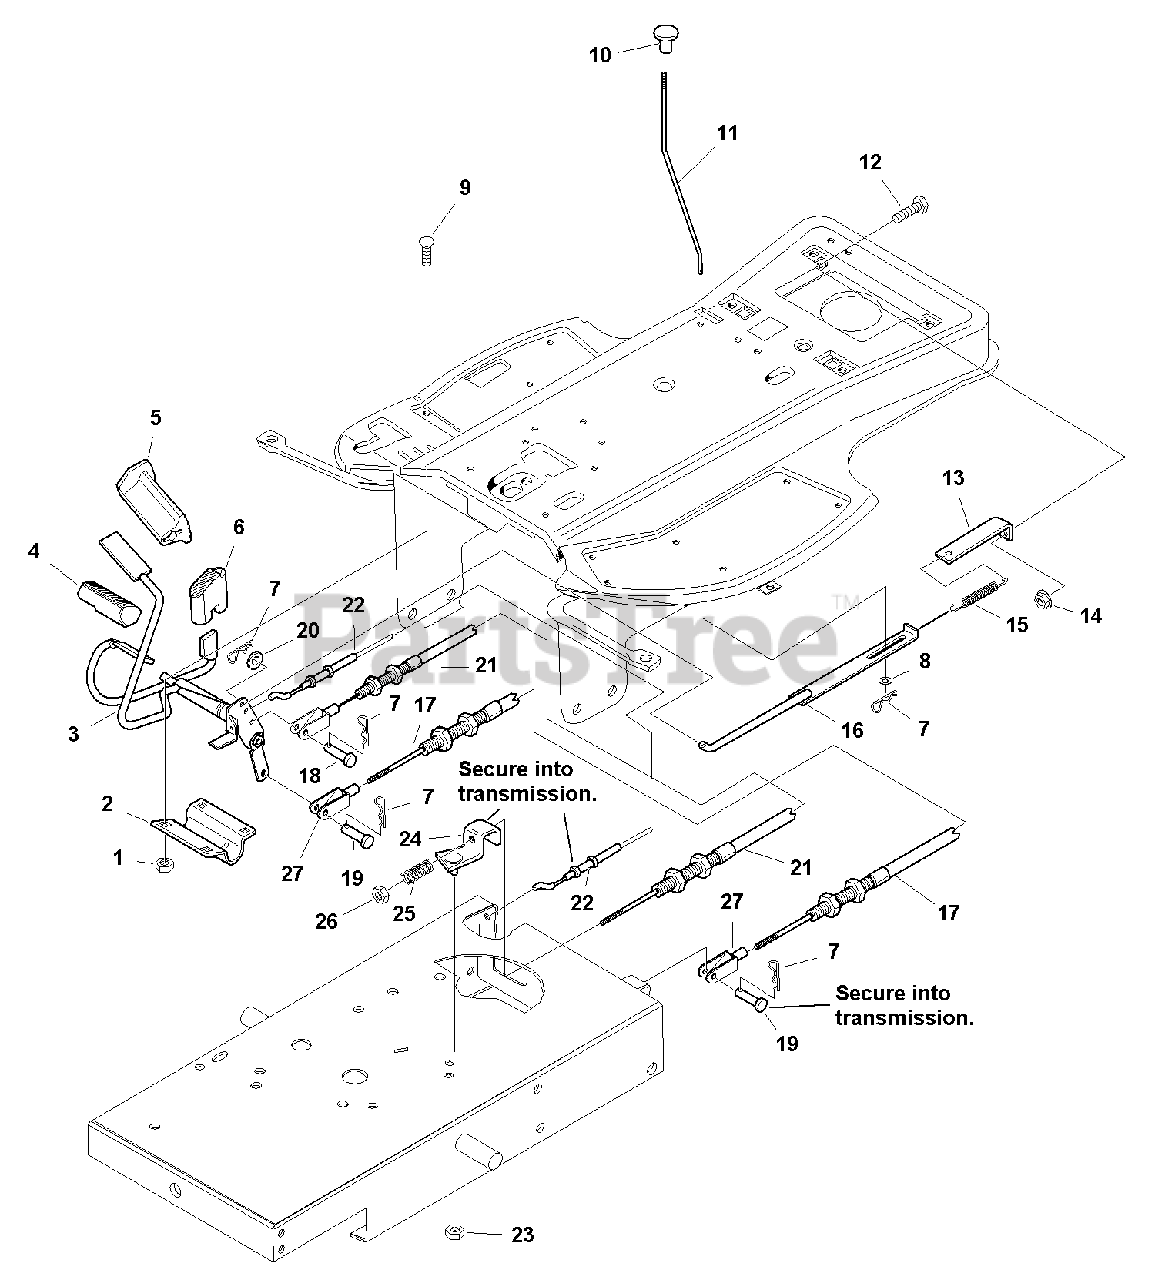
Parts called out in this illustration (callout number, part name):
1	NUT, Hex Lock ESNA, 5/16-18, Black
3	FOOT PEDAL & BRAKE ARM ASSEMBLY
4	PEDAL, Foot, Forward
5	PAD, Brake Pedal
6	PEDAL, Foot, Reverse
7	CLIP, Hair Pin, Black
8	WASHER, 1/4, Black
9	CARRIAGE BOLT, 5/16-18 x 3/4, Black
10	KNOB, 1/4-20 Thread
11	ROD, Parking Brake, Yellow
12	CAPSCREW, Hex Head, Whiz Lock 5/16-18 x 3/4, Black
13	BRACKET
14	NUT, Hex, 5/16, Black
15	SPRING, Extension, 6-1/2" Long
16	LEVER & ROD ASSEMBLY
17	CABLE, Forward/Reverse
18	PIN, Yoke, Drilled, 1/4 x 3/4, Black
19	PIN, Clevis, 11/32 x 1-1/4
20	WASHER, 5/16, Black
21	CABLE, Brake Control
22	CABLE, Clutch Control
23	NUT, Hex Flange Lock, 5/16-18, Black
24	GUIDE BELT & STUD ASSEMBLY
25	SPRING, Compression
26	NUT, Hex Center Lock, 1/4-20
